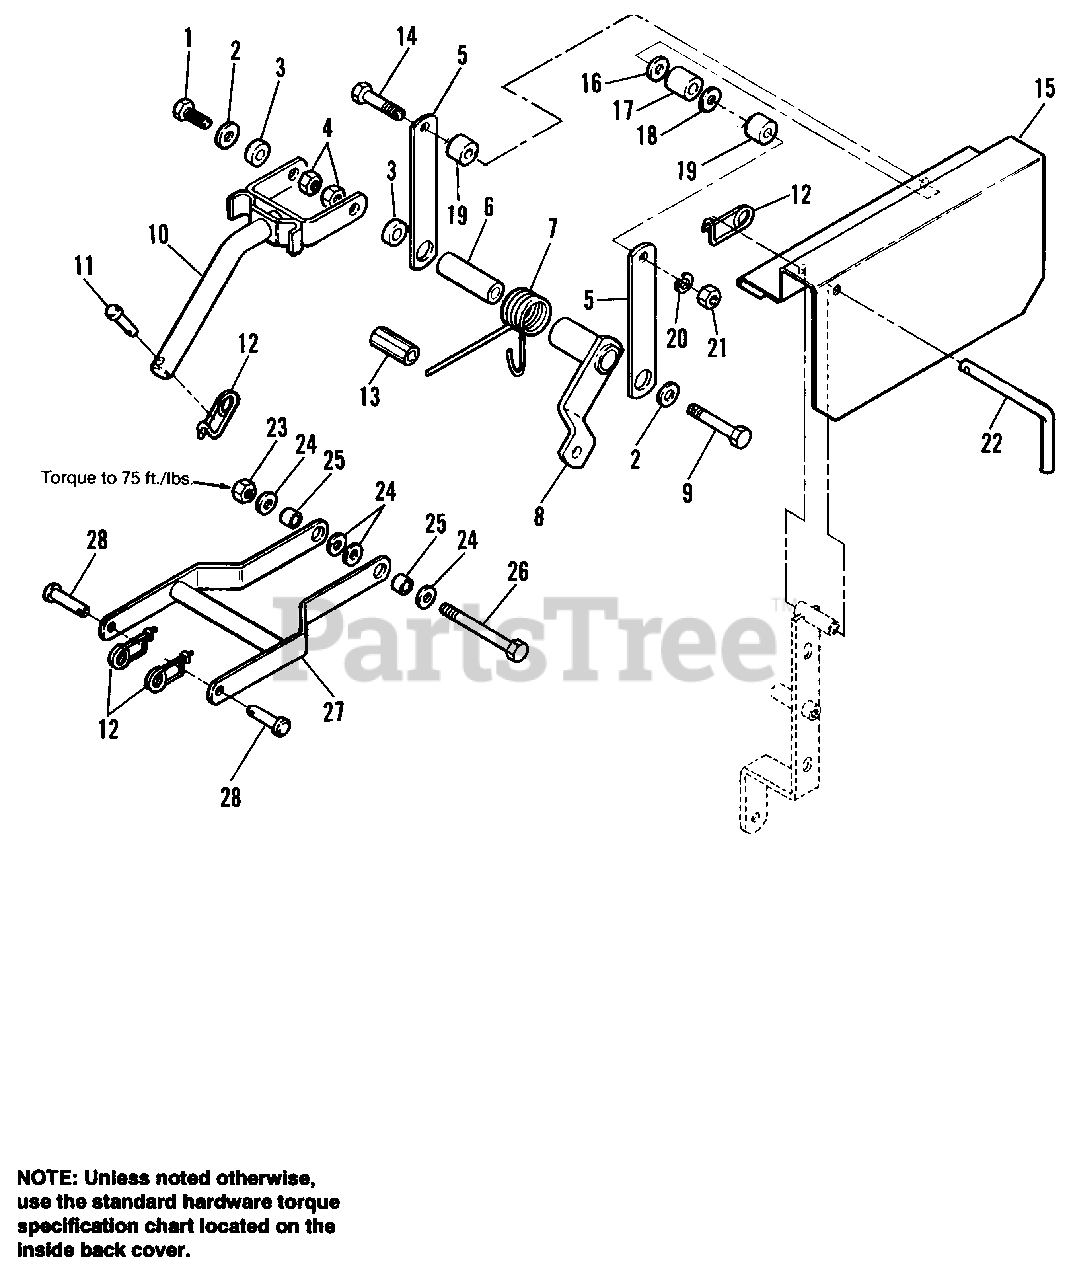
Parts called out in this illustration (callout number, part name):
1	CAPSCREW, Hex, 7/16-14 x 1-1/4
2	WASHER, Plain, 3/8
4	LOCKNUT, Flange, 7/16-14
5	SUPPORT, Rear Belt Guard
7	SPRING, Torsion
8	LEVER ASSY., Clutch
9	CAPSCREW, Hex Hd., 7/16-14 x 3-1/2
10	BAR ASSY., Lift
11	PIN
12	CLIP, Safety
13	ANCHOR, Spring
14	CARRIAGE BOLT, 5/16-18 x 2-3/4
15	GUARD, Belt
16	WASHER, Nylon
17	SPACER
20	LOCKWASHER, 5/16
21	NUT, Hex, Full, 5/16-18
23	LOCKNUT, Hex, 1/2-13
24	WASHER, Plain, 1/2
26	CAPSCREW, Hex, 1/2-13 x 5
27	FRAME ASSY.
